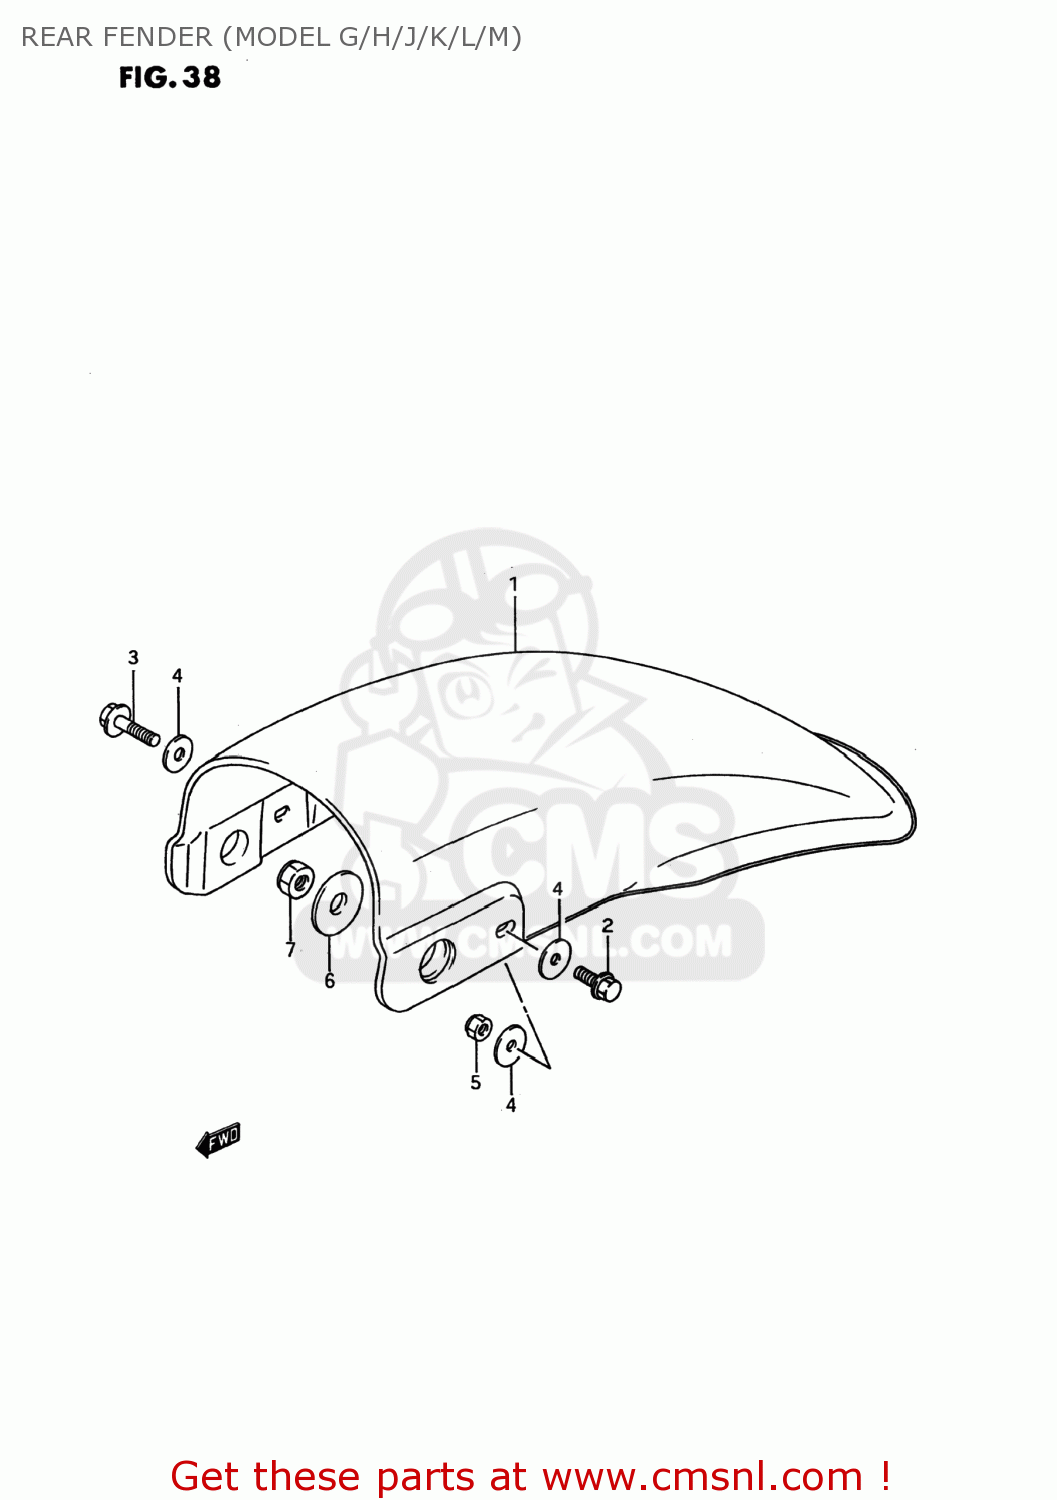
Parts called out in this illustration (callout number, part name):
1	FENDER,RR
2	BOLT
3	BOLT
4	WASHER
5	NUT
6	WASHER (10.5X30X2.3)
7	NUT
